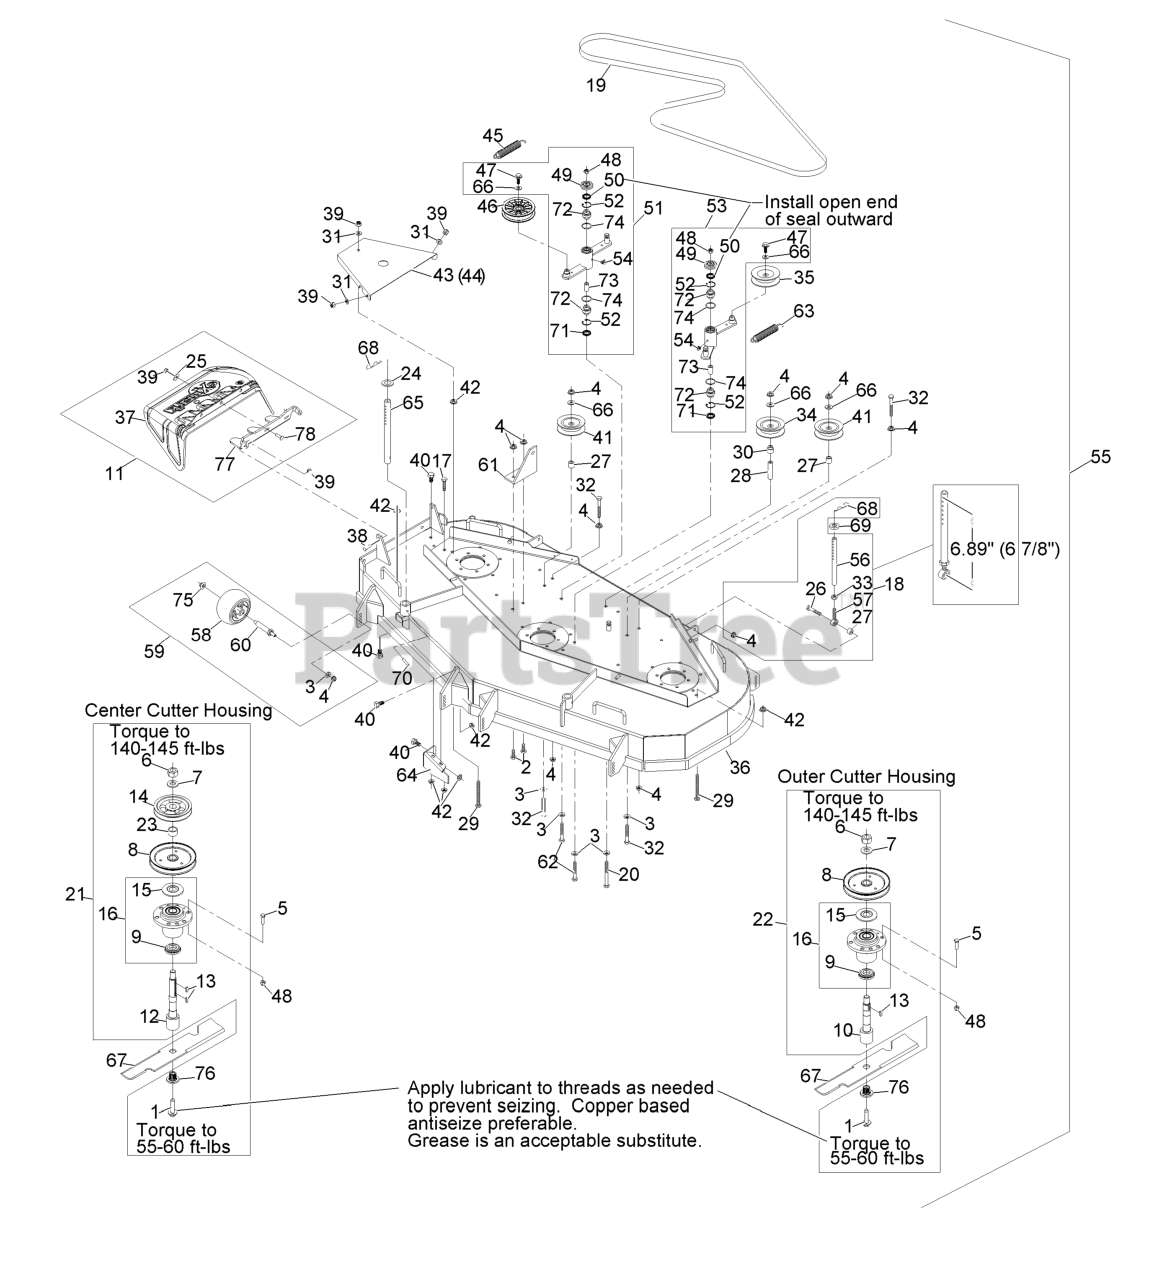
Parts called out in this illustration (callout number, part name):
1	SCREW,SEMS 1/2-20 X 2.19
2	SCREW-HH
3	WASHER-BELLEVILLE
4	NUT-HHF, WHIZ
5	SCREW-HH
8	SHEAVE,BLADE DRIVE 6.30
9	SPACER-GUARD, BOTTOM
10	KIT, SPLINED SPINDLE 103-
11	ASM,FMD DISCHARGE CHUTE
12	KIT, SPLINED SPINDLE 103-
14	SHEAVE,BLADE DRIVE
15	GUARD-BEARING, TOP
16	KIT, CUTTER HOUSING
17	SCREW-HH
18	KIT,SUPPORT LINK W/PIN
19	BELT,MULE DRIVE
20	SCREW-HH
21	ASM, CUTTER HSG FMD604CTR
22	ASM, CUTTER HSG COMPLETE
23	SPACER,TUBE
24	SPACER-DECK SUPPORT
25	WASHER-FLAT
26	SCREW-HH
28	SPACER-ANCHOR, CLUTCH
29	BOLT,TAP HH
30	BUSHING,IDLER
31	WASHER-FLAT
32	BOLT-CARR
33	NUT-HJ
34	PULLEY-IDLER
35	PULLEY-IDLER
36	ASM, DECK W/ DECALS FMD60
37	CHUTE,DISCHARGE
38	SCREW-HH
39	NUT-LOCK, NI
40	SCREW-HH
41	IDLER,PULLEY
43	SHIELD,BELT RH
44	SHIELD,BELT LH
45	SPRING-EXTENSION
46	PULLEY-IDLER, FLAT
47	SCREW-HHF
48	NUT-LOCK, NI
49	GUARD-TOP
50	SEAL-LIP, SINGLE
51	KIT, IDLER ARM W/BEARINGS
52	RING-SNAP
53	KIT, IDLER ARM W/BEARINGS
54	FITTING-GREASE, 90 DEG
55	Complete Deck Assy
56	LINK,SUPPORT
57	BALLJOINT
58	ROLLER-SCALP, ANTI
61	BRACKET,SPRING ANCHOR
62	SCREW-HH
63	SPRING-EXTENSION
64	BAFFLE,DISCHARGE
65	ROD,DECK SUPPORT
66	WASHER-FLAT
68	PIN,HAIR COTTER
71	SEAL-LIP, DOUBLE
72	BEARING-SPHERICAL
73	BUSHING-LEVER, LIFT
75	Nut-Nyloc 3/8-16 Flg
76	BUSHING,SPLINED
77	BRACKET, DISCHARGE CHUTE
78	SCREW-CARR
